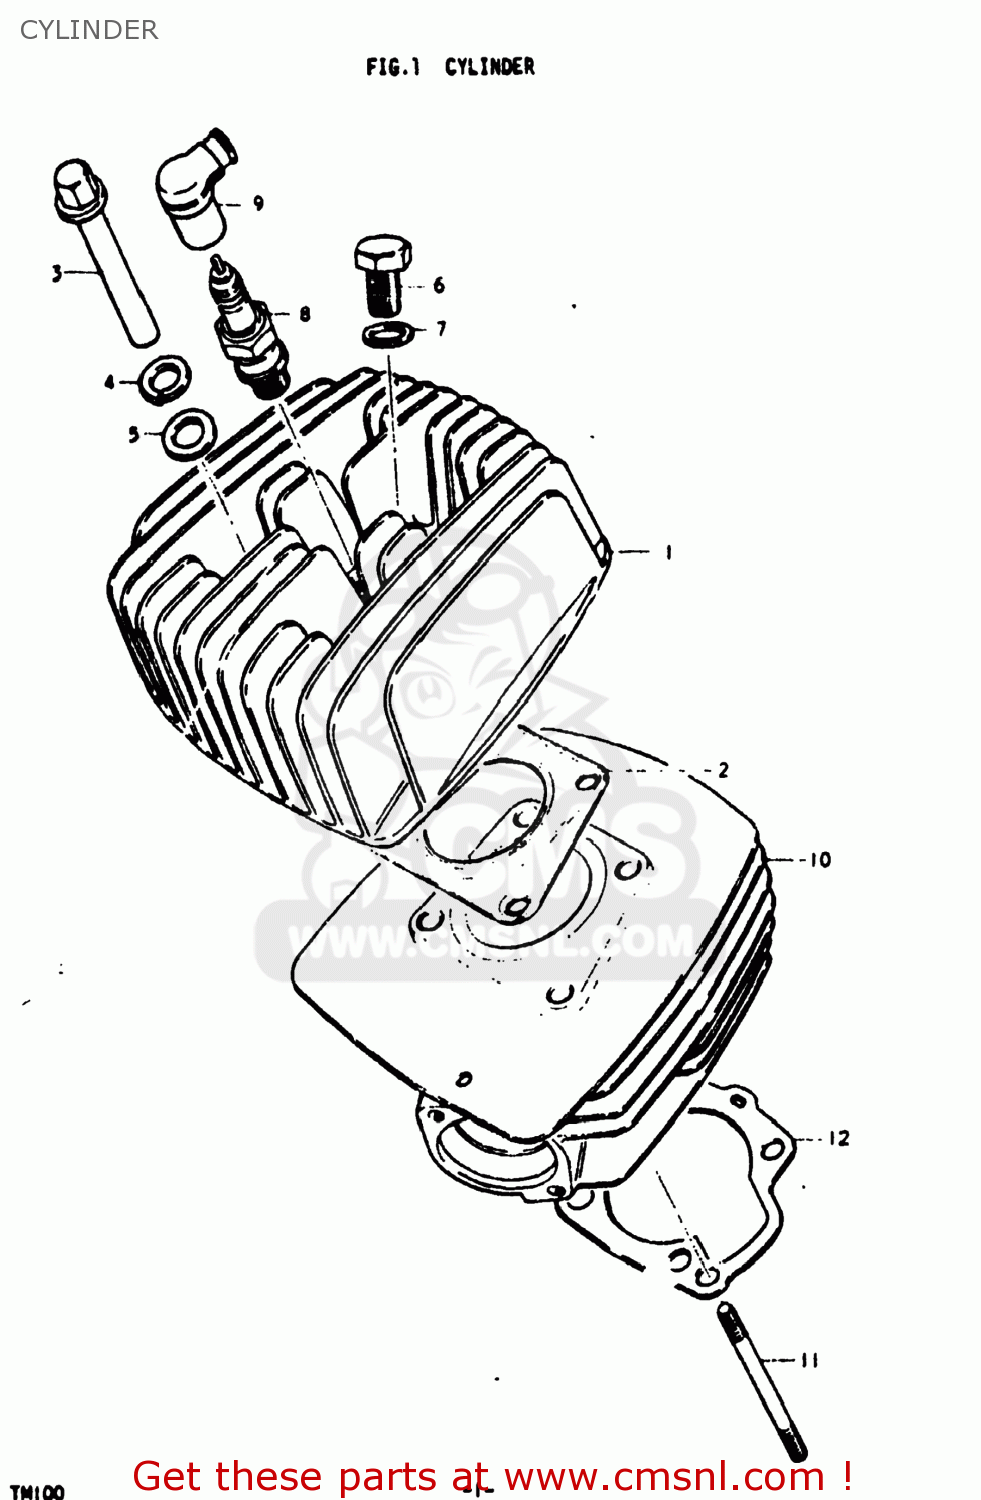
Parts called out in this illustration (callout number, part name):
1	HEAD,CYLINDER
2	GASKET,CYLINDER HEAD (NAS)
3	NUT
4	WASHER,LOCK 12
5	WASHER
6	PLUG
7	GASKET(14X19.2X2) (NAS)
8	SPARK PLUG
9	CAP ASSEMBLY,SPARK PLUG
10	CYLINDER
11	STUD 8X65
12	GASKET,CYLINDER (MCA)
